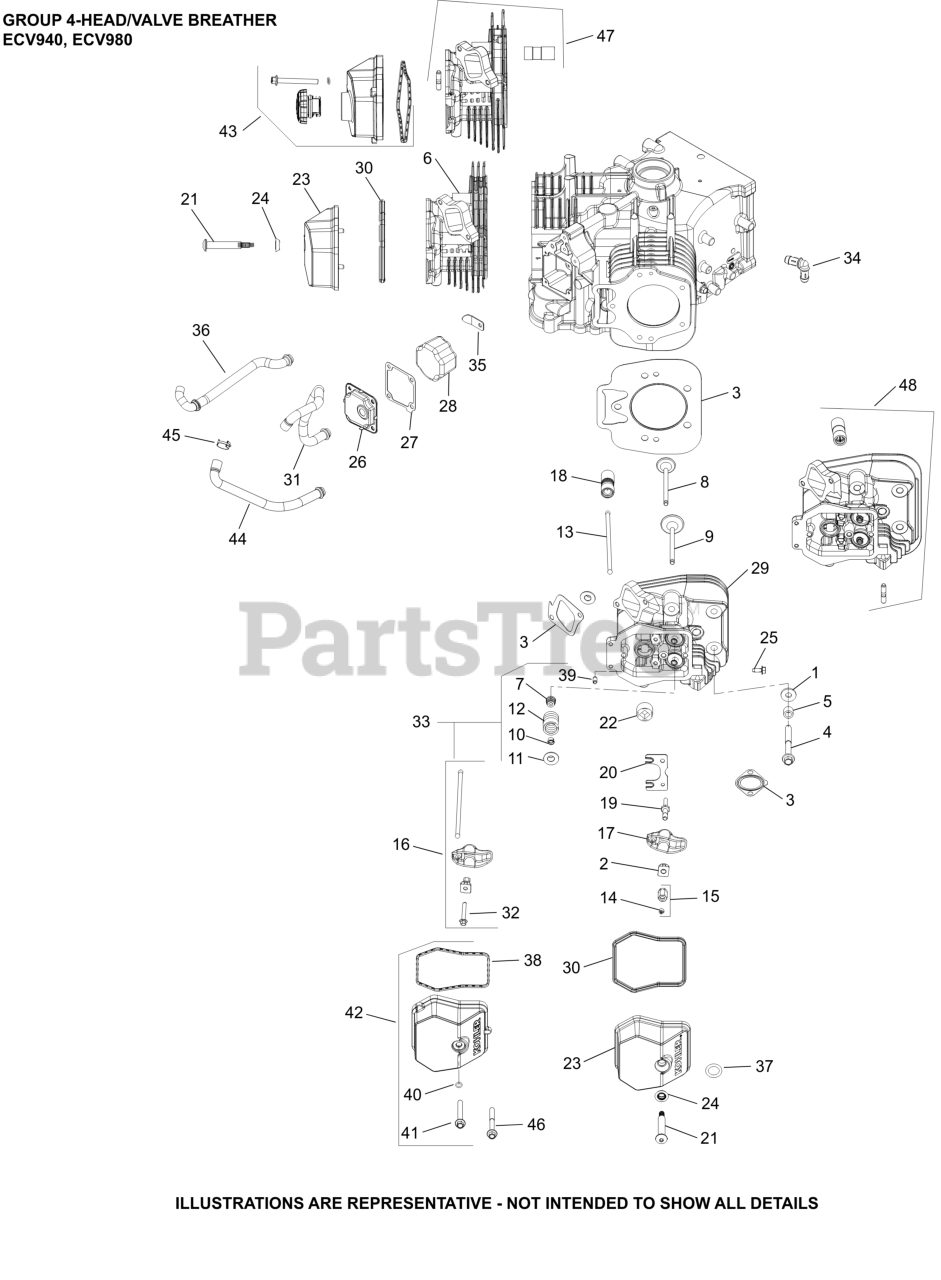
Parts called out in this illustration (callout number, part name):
1	WASHER, FLAT 13/32"
2	PIVOT, ROCKER ARM
3	KIT, CYLINDER HEAD GASKET
4	SCREW, FLG M10X1.5X90
7	SEAL, VALVE BAND
8	VALVE, EXHAUST
9	VALVE, INTAKE
10	KIT, RETAINER
11	CAP, VALVE SPRING
12	SPRING, VALVE
13	ROD, PUSH
17	ARM, ROCKER
18	LIFTER, VALVE HYDRAULIC-USE 25 351 11-S
22	PLUG, PIPE 3/4 NPTF SQUARE
25	SCREW, THREAD FORMING
26	KIT, BREATHER ASSEMBLY
27	GASKET, BREATHER
40	O-RING, VALVE COVER SCREW
42	KIT, VALVE COVER ASSEMBLY
44	CLAMP, SPRING HOSE
45	HOSE, BREATHER (ETB)
46	SCREW, HEX FLANGE
47	KIT, #1 CYLINDER HEAD COMPLETE
48	KIT, #2 CYLINDER HEAD COMPLETE
NI	SCREW, HEX FLANGE
NI	PIN, ROLL
NI	SEAL, ALUMINUM VALVE COVER (BLUE)
NI	FILTER, BREATHER
NI	KIT,VALVE CVR (NO FILL)-USE 62 096 50-S
